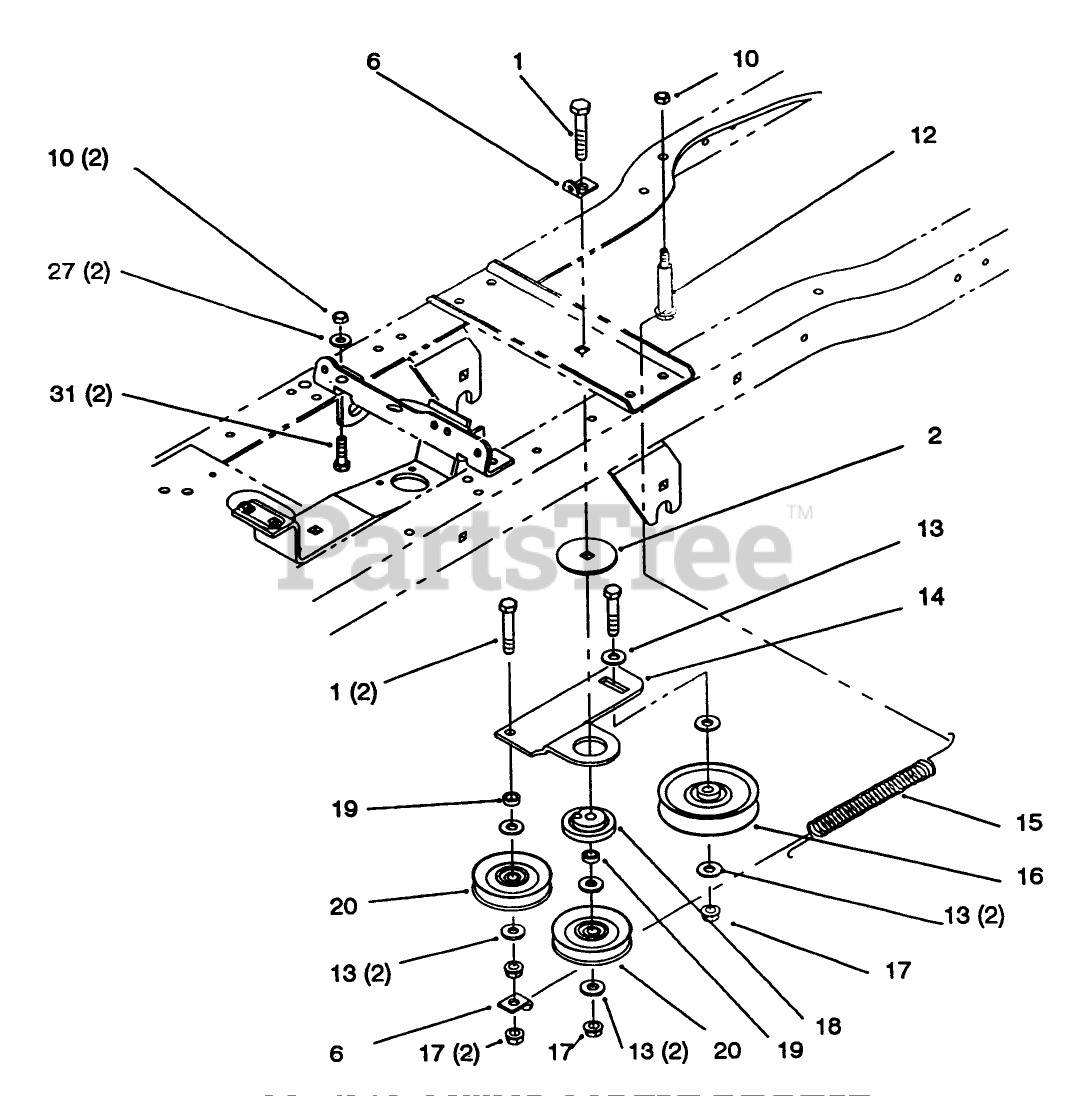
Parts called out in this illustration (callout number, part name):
1	SCREW-HH
2	WASHER-BEARING
6	CLIP - SPRING
10	NUT-LOCK, NI
12	BOLT-SHOULDER
13	WASHER-FLAT
14	ARM - IDLER
15	SPRING - CLUTCH
16	PULLEY-IDLER, FLAT
17	NUT-LOCK, NI
18	BUSHING
19	Spacer (Only On: 72043, 72103, 72063, 72083)
20	PULLEY-IDLER
27	WASHER-PLAIN
31	SCREW-HH
